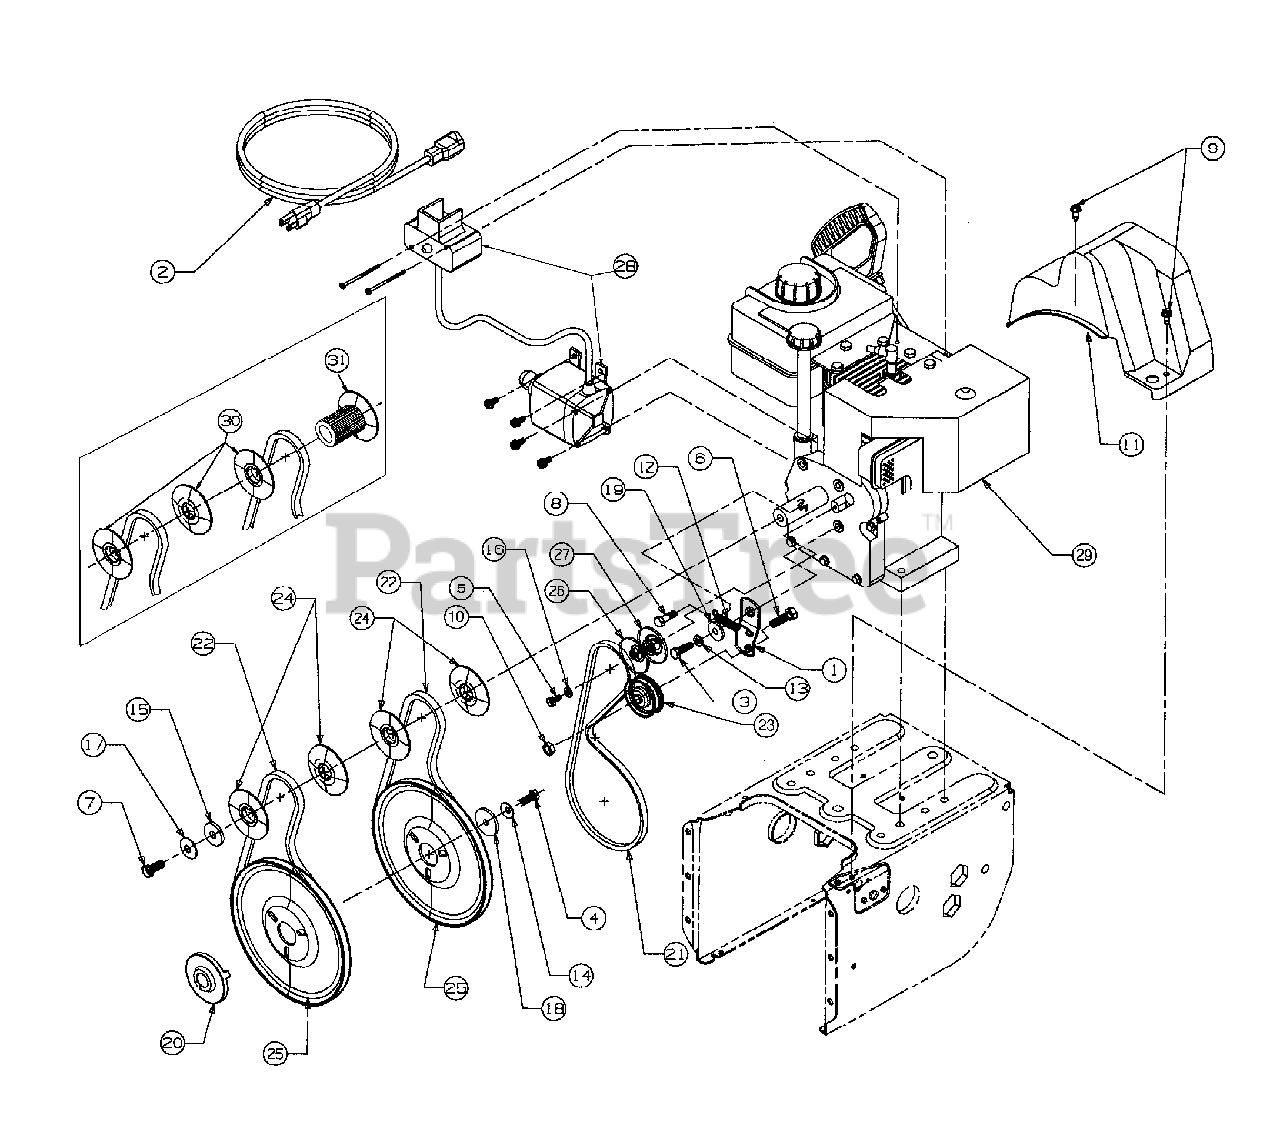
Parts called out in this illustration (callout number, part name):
3	Screw
4	Screw
5	Screw
6	Screw
7	Screw
8	Screw
9	Screw
10	Nut, Hex
11	Belt Cover
12	Spring
13	Washer - Flat
14	Washer - Bell
15	Washer - Flat
16	Washer - Lock
17	Washer - Bell
18	Washer - Flat
19	Shoulder Spacer
20	Pulley, Adapter
21	V-Belt
22	V-Belt Matched
23	Idler, Flat
24	Pulley, Half
25	Pulley - Auger
26	Pulley Half
27	Pulley Half
28	Starter
29	Engine
30	Pulley, Half
31	Pulley, Half
